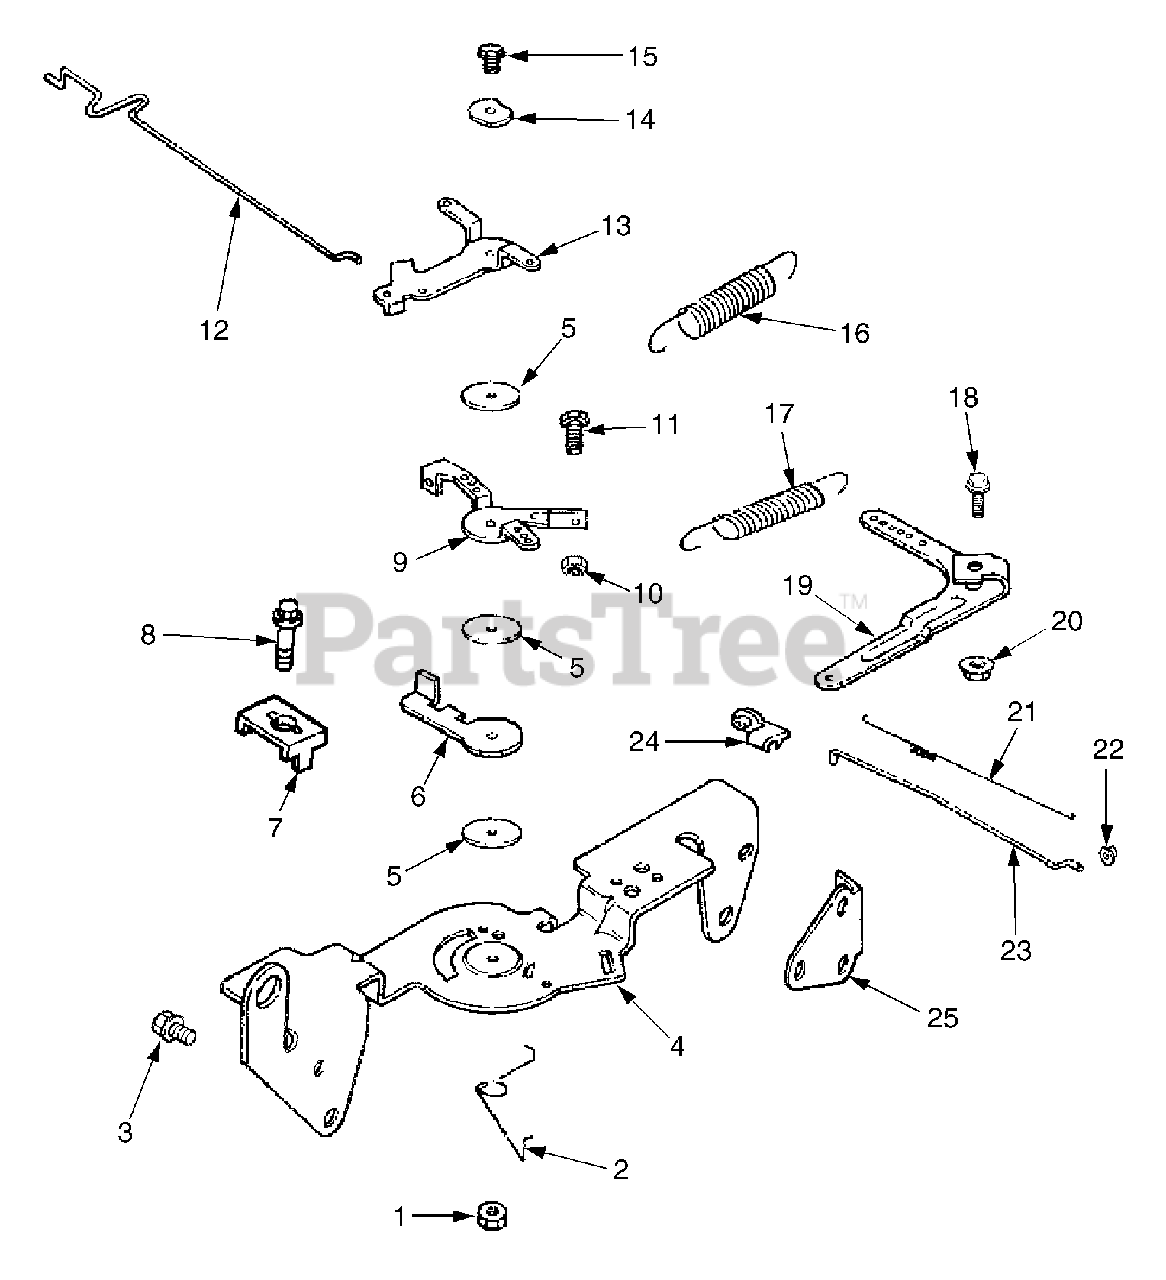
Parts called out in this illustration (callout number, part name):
1	Nut, Hex Lock M5 x 0.8
2	Spring, Choke Return
3	Screw, Hex Flange M6 x 1.0 x 16
4	Bracket, Control
5	Washer, Plain 5.5 mm
6	Lever, Throttle Actuator
7	Clamp,Cable,
8	Screw, Hex Flange M5 x 0.8 x 16
9	Lever, Throttle Control
10	Nut, Hex M4 x 0.7
11	Screw, Hex Cap M4 x 0.7 x 30
12	Linkage,Choke
13	Lever, Choke
14	Washer, Spring 1/4"
15	Screw, Hex Flange M5 x 0.8 x 20
16	Spring, Throttle Limiter
17	Spring, Gov., (6mm Gov. Shaft)
18	Screw, Hex Flange (6mm)
19	Lever, Governor (6mm)
20	Nut, Hex Flange M6 x 1.0"
21	Spring, Linkage
22	Bushing, Linkage Retaining
23	Linkage, Throttle
24	Bushing, Linkage Retaining
25	Bracket Support
